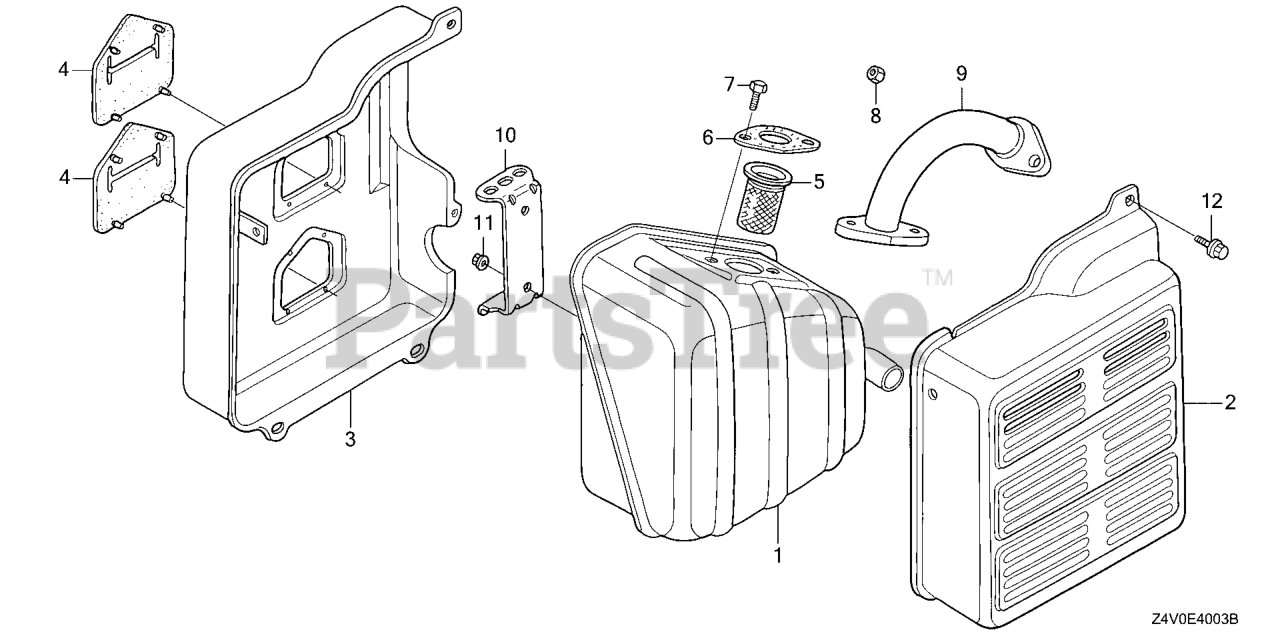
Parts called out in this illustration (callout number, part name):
1	MUFFLER
2	PROTECTOR, MUFFLER (OUTER)
3	PROTECTOR, MUFFLER (INNER) (DENYO)
4	SEAL, MUFFLER PROTECTOR
5	ARRESTER, SPARK
6	GASKET, MUFFLER
7	BOLT, HEX. (8X20)
8	NUT, HEX. (8MM)
